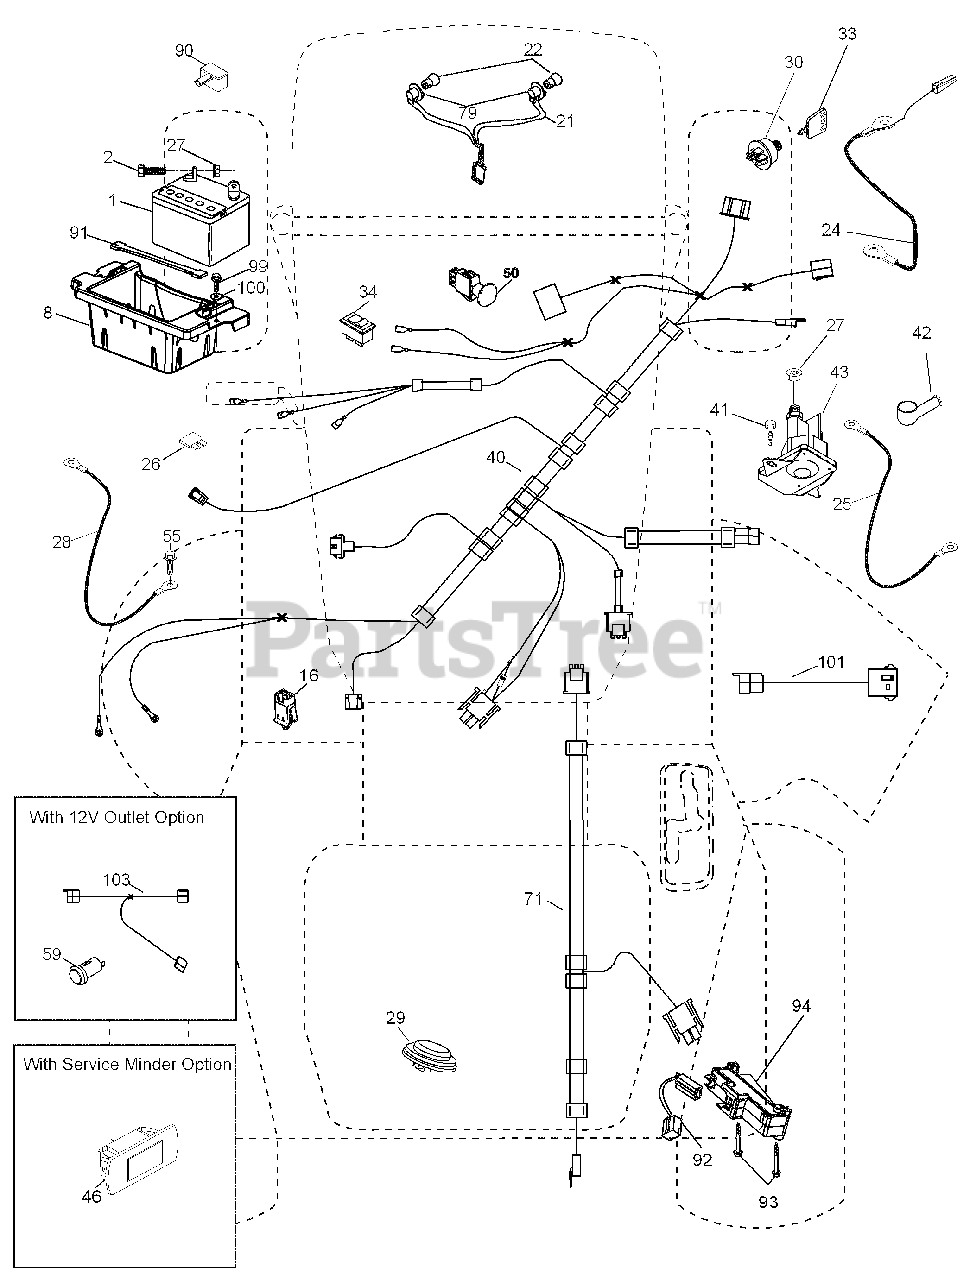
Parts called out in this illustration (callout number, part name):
1	Battery
2	Bolt Hex Head 1/4-20 x 3/4
8	Box Battery
16	Switch Interlock Push-In
21	Harness Socket Light w/4152J
22	Bulb, Light
24	Cable Battery
25	Cable Start Red 17.5"
27	Nut Keps Hex 1/4-20 unc
28	Cable, Ground
29	Switch, Seat
30	Switch Ignition
34	Switch Light/Reset
40	Harness Ign Dash
41	Screw Thd Cut 1/4-20 x 1/2
42	Cover Terminal
43	Solenoid
46	Gauge Hourmeter
50	Switch, PTO
55	Screw Thdrol 5/16-18 x 3/4 TYTT
59	Outlet 12-Volt
71	Harness Ignition, Chassis
79	Bulbholder Asm. Incandescent
90	Cover Terminal Battery
91	Strap Battery Mount Front
92	Harness Pigtail
94	Module Reverse
99	Screw Hexwsh Thdrol 1/4-20 x 3/4
100	Washer 9/32 x 7/8 x 16 Ga.
101	Pigtail MATNLK
103	Harness Pigtail 12V Outlet
